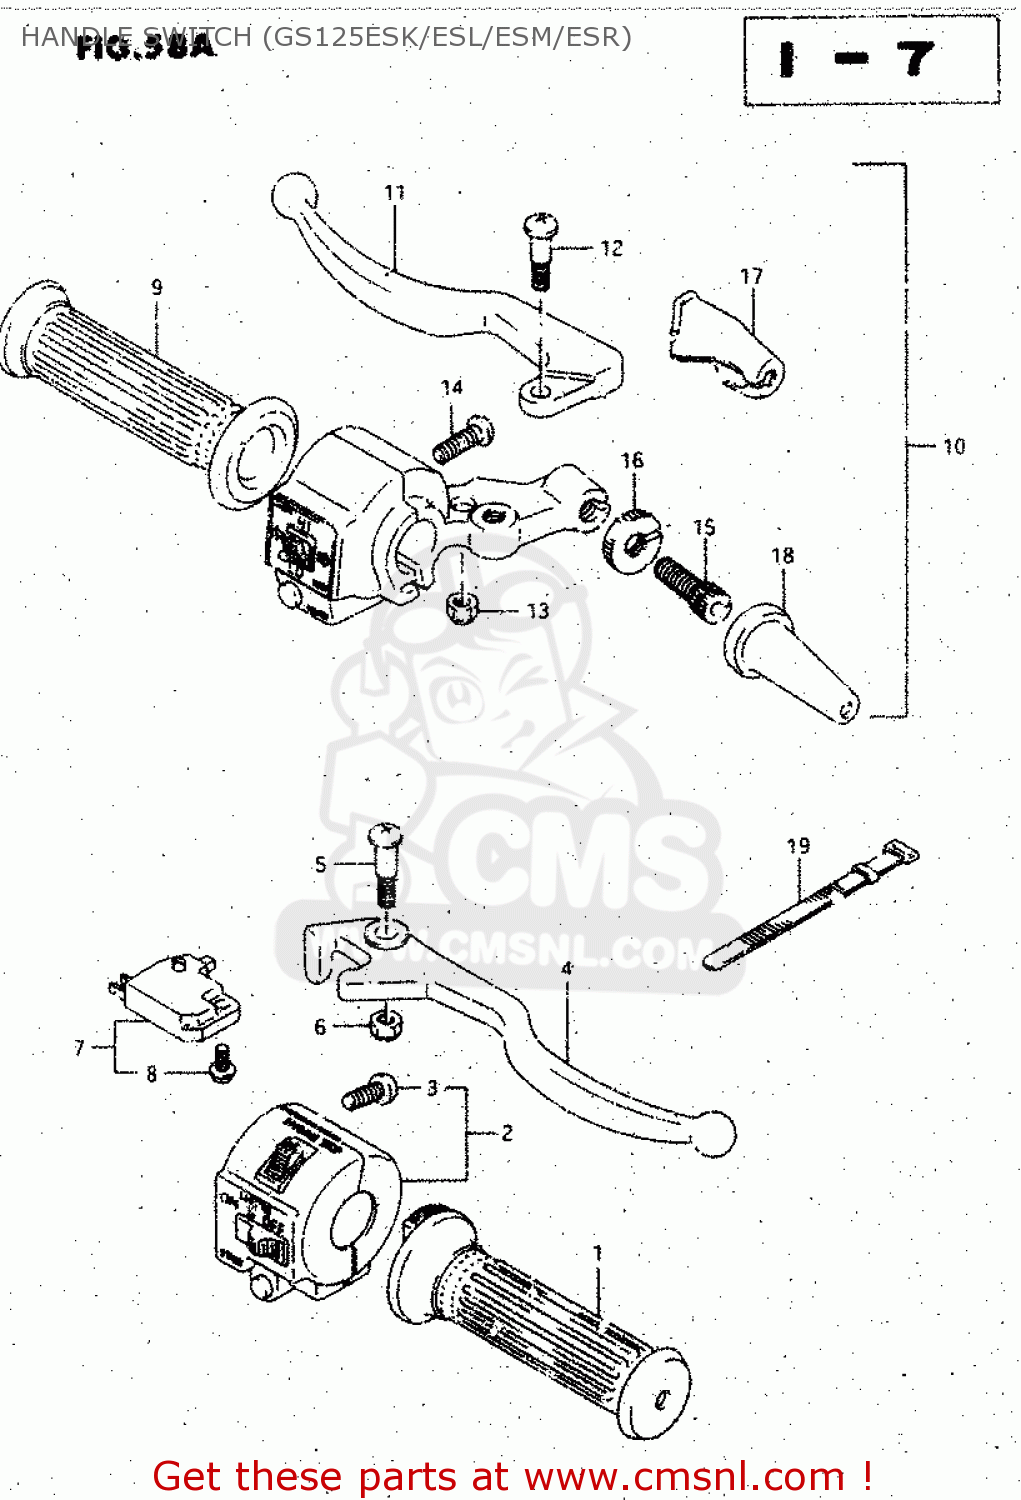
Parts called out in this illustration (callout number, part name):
1	GRIP,THROTTLE
2	SWITCH ASSY,HANDLE,R
3	SCREW 5X20
4	LEVER,BRAKE
5	SCREW
6	NUT
7	SWITCH ASSEMBLY,STOP
8	SCREW
9	GRIP, LH
10	LEVER ASSY,CLUTCH
11	LEVER,CLUTCH
12	SCREW
13	NUT
14	SCREW
15	ADJUSTER,CABLE
16	NUT,CABLE ADJUSTER
17	COVER,CLUTCH LEVER
18	BOOT,CLUTCH CABLE
19	CLAMP(L:120)
